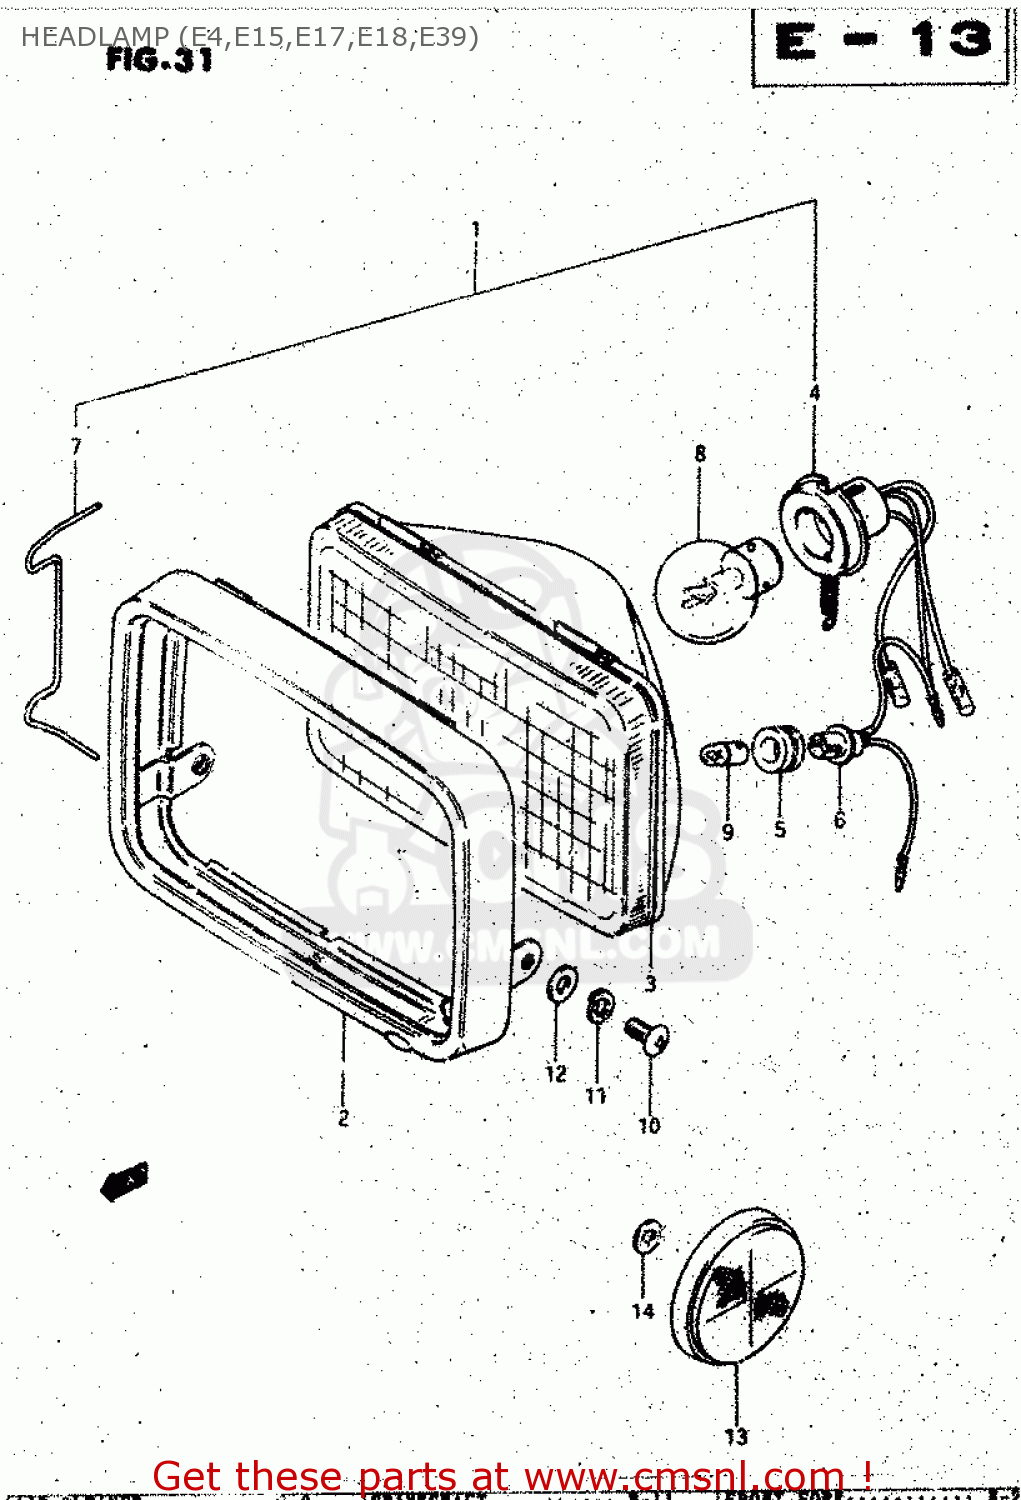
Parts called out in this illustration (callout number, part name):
1	HEADLAMP ASSY
2	RIM
3	UNIT
4	SOCKET
5	JOINT,RUBBER
6	SOCKET
7	SPRING
8	BULB
9	BULB(12V4W)
10	SCREW
11	LOCK WASHER
12	WASHER
13	REFLEX REFLECTOR,FR
14	WASHER
